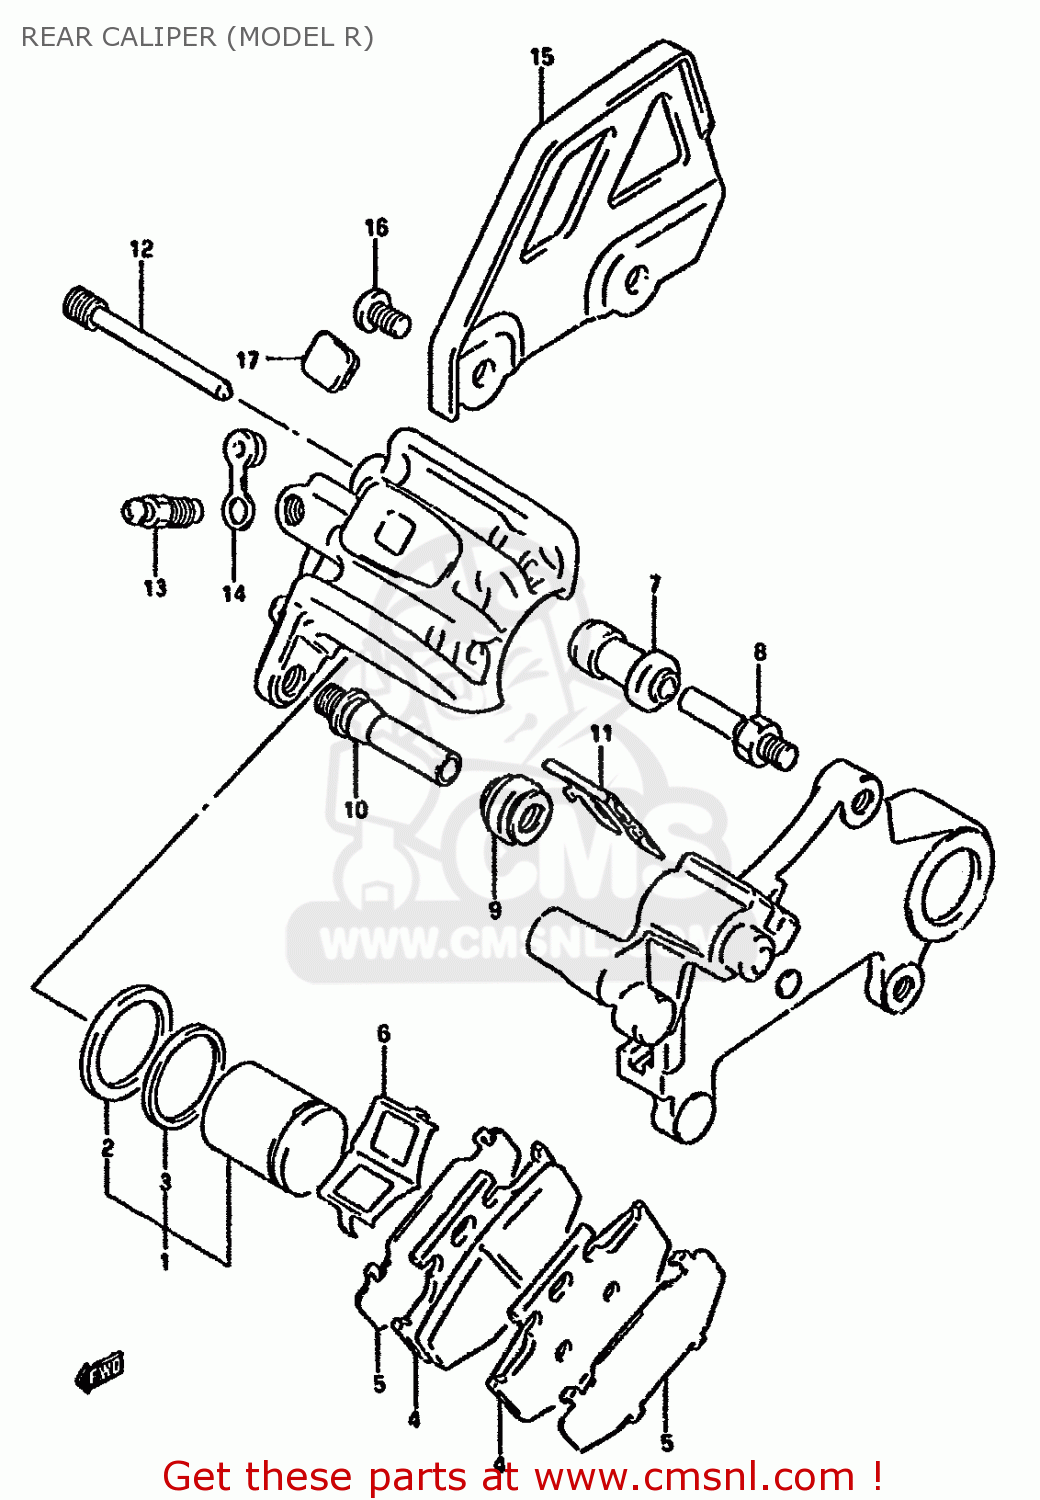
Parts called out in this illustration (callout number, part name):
1	PISTON SET
2	SEAL,PISTON
3	SEAL
4	PAD (MCA)
5	SHIM
6	SPRING,PAD
7	BOOT
8	PIN,BOLT
9	BOOT
10	PIN
11	RETAINER,BRACKET
12	PIN,HANGER
13	BLEEDER
14	CAP,BLEEDER
15	GUARD,RR CALIPER
16	SCREW 6X12
17	COVER,RR CALIPER BODY
18	COVER,RR CALIPER BODY
